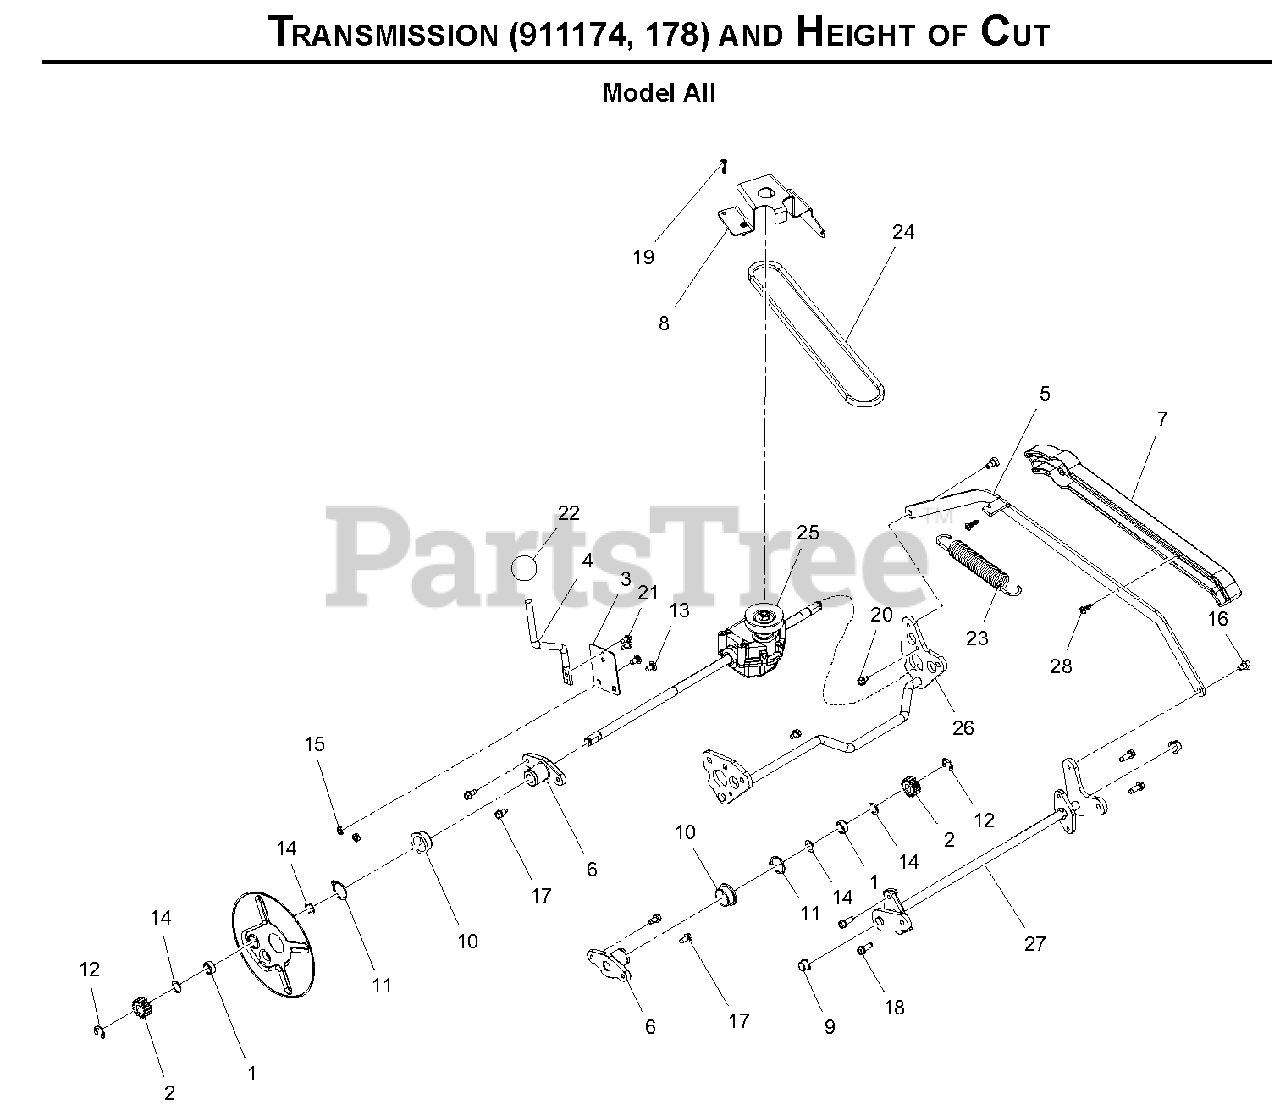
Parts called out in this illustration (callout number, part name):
1	SPCR, PM .500ID X .75OD X .321
2	GEAR, PINION , LM WHEEL DRIVE
3	PLATE, HOC SPRING
4	LEVER, HOC ADJUST
5	LINK, HOC CONNECT
6	HUB, LM REAR AXLE
7	COVER, LINK ROD
8	GUIDE, BELT TRANSMISSION
9	BSHG, SPLIT NYLON
10	BSHG, FLANGE 1.0x1.125x.50x1.375
11	RG-RTNG-EXT 1.00X.042
12	RG-RTNG-EXT .500X.042 (E)
13	@BLT-RDHDSQNK .25-20X.50 G5 Y
14	WASHER-FLAT-STL, .500 X .750 X .020
15	@NUT-LK-CTR-JAM .25-20 YWZC
16	BOLT, SHLDR .320X.210X.25-20 SELF-TAPPING
17	SCR-TAP .25-20X.50 HWH TR YWZ
18	SCR-TAP .25-20X.75 HWH TR YWZ
19	SCR-TAP #10-14X.75 PLASTITE BLZC
20	SCR-TAP .25-20X.37 HWH YWZ TR
21	SCR-TAP 12-24X.50 HWH TR YWZC
22	KNOB,BALL -BLACK 1.47" .375-16
23	SPRG, EXTENSION
25	TRANSAXLE, AUTOMATIC, LM, 9:1
26	WLDMT, LM REAR AXLE
27	WLDMT, LM FRONT AXLE
28	SCR-TAP #12-14X.75 PLASTITE BLZC
